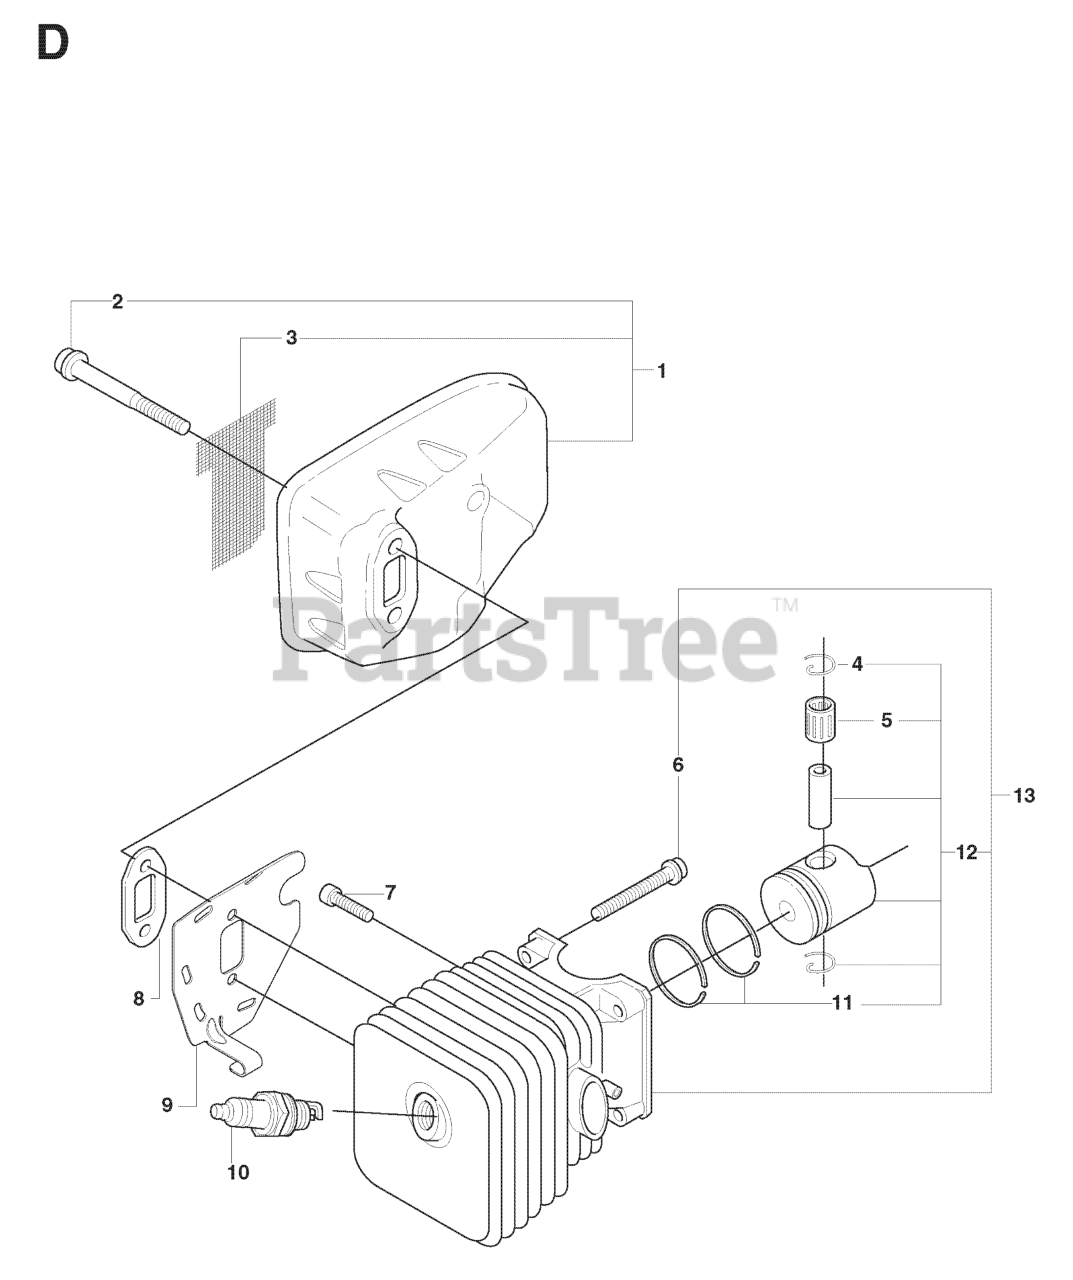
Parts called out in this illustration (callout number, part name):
6	SCREW MC6S 5X35
7	SCREW
9	AIR CONDUCTOR
10	SPARK PLUG RCJ7Y
11	PISTON RING
